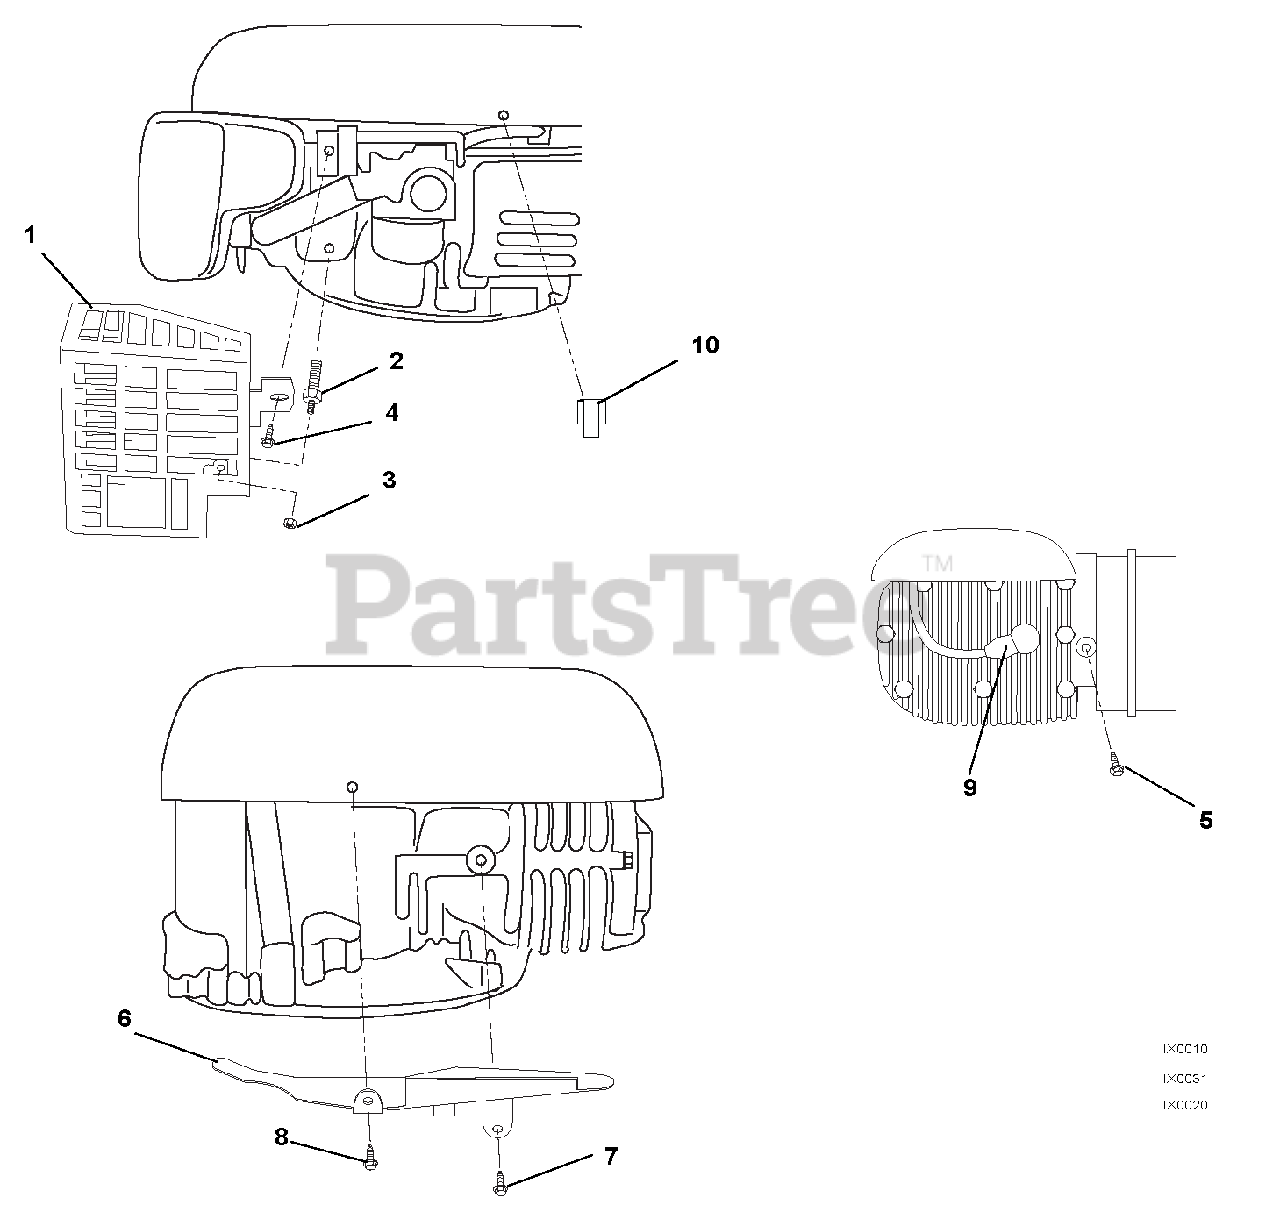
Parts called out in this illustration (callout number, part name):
1	GUARD-MUFFLER-STRING TRIM CE
2	SCR-SPECIAL .25-20X1/10-24X.31
3	@NUT-LK-NYL 10-24 W/INSRT YWZC
4	@SCR-TAP 10-24X.50 HWH TR YWZC
5	@SCR-TAP .25-20X.50 HWH TR YWZ
6	GUARD-FLYWHEEL-LARGE STRTRM CE
7	@SCR-TAP .25-20X.37 HWH YWZ TR
8	SCR-TAP 8-15X.38 CR RH A YWZC
9	SHIELD, SPARK PLUG
10	CLIP, FINGER GUARD
